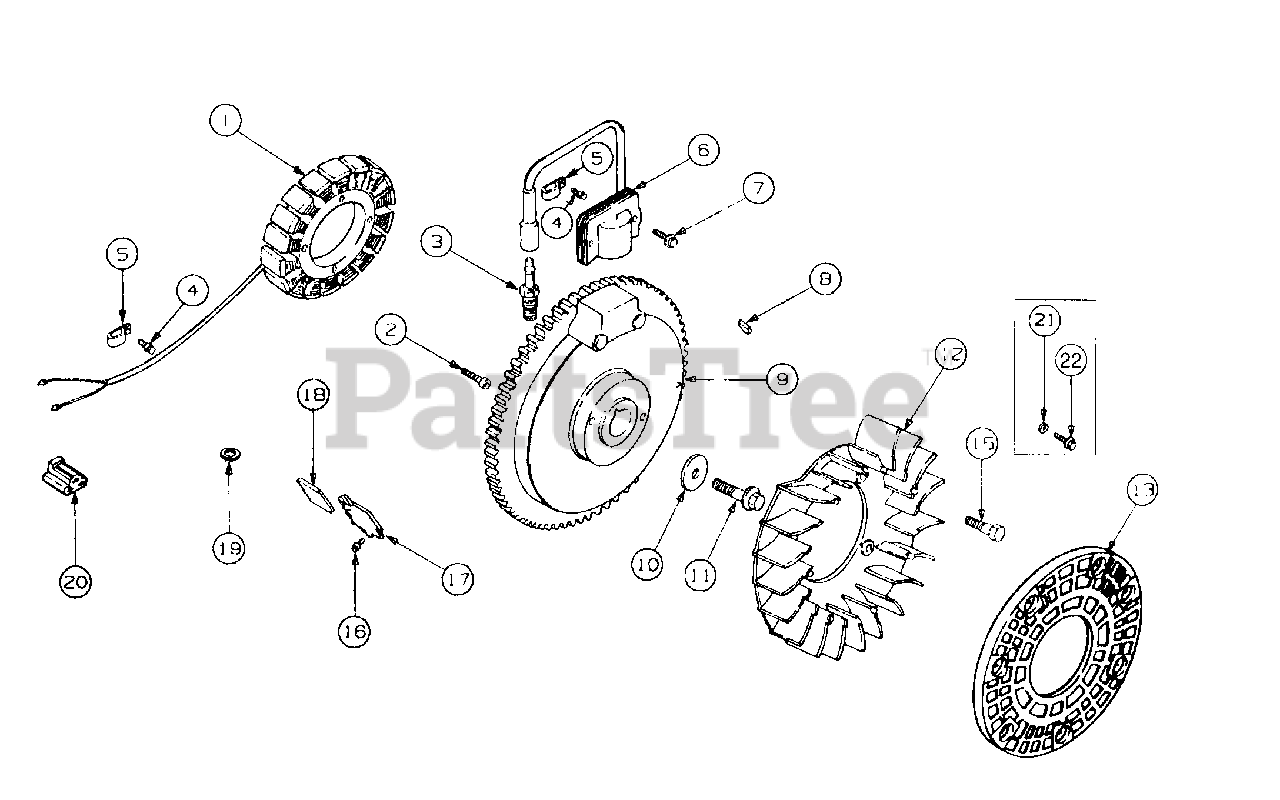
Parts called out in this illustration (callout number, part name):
1	Kit, Stator
2	Screw, Stator Mntg, M5 x .8 x 25
3	Spark Plug
4	Screw, Harness Clip, M5 x .8 x 10
5	Clip, Cable
6	Module, Ignition
7	Screw, Ign Module, M5 x .8 x 20
9	Flywheel Assembly
10	Washer, Flywheel
11	Screw, Flywheel, M10 x 1.5 x 46
12	Fan
13	Screen, Grass
15	Bolt, Shoulder M6 x 1 x 16
16	Screw, Rectifier, M6 x 1 x 16
17	Rectifier-Regulator
18	Connector, Three Contact
19	Washer, Lock, 1/4
20	Connector, Three Contact
21	Spacer
22	Screw
